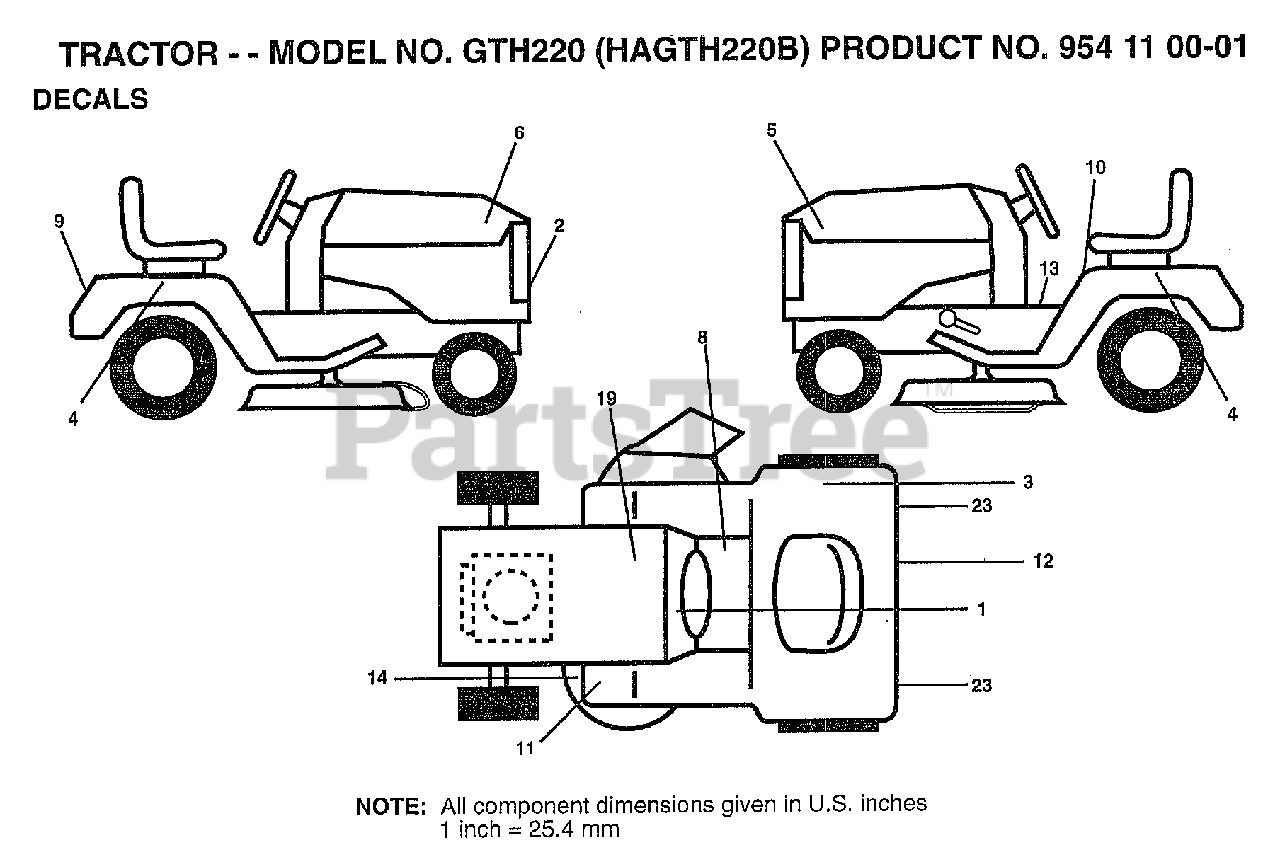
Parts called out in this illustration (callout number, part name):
1	DECAL, OPERATING INSTRUCTION
2	DECAL.GRILLE.HUSQ
4	DECAL FENDER AUTO
5	DECAL.INST.HD.LH.
6	DECAL.INST.HD.RH.
9	DECAL.FENDER.
10	"DECAL-FENDER,DANG"
14	"DECAL-SCHEM,BELT"
